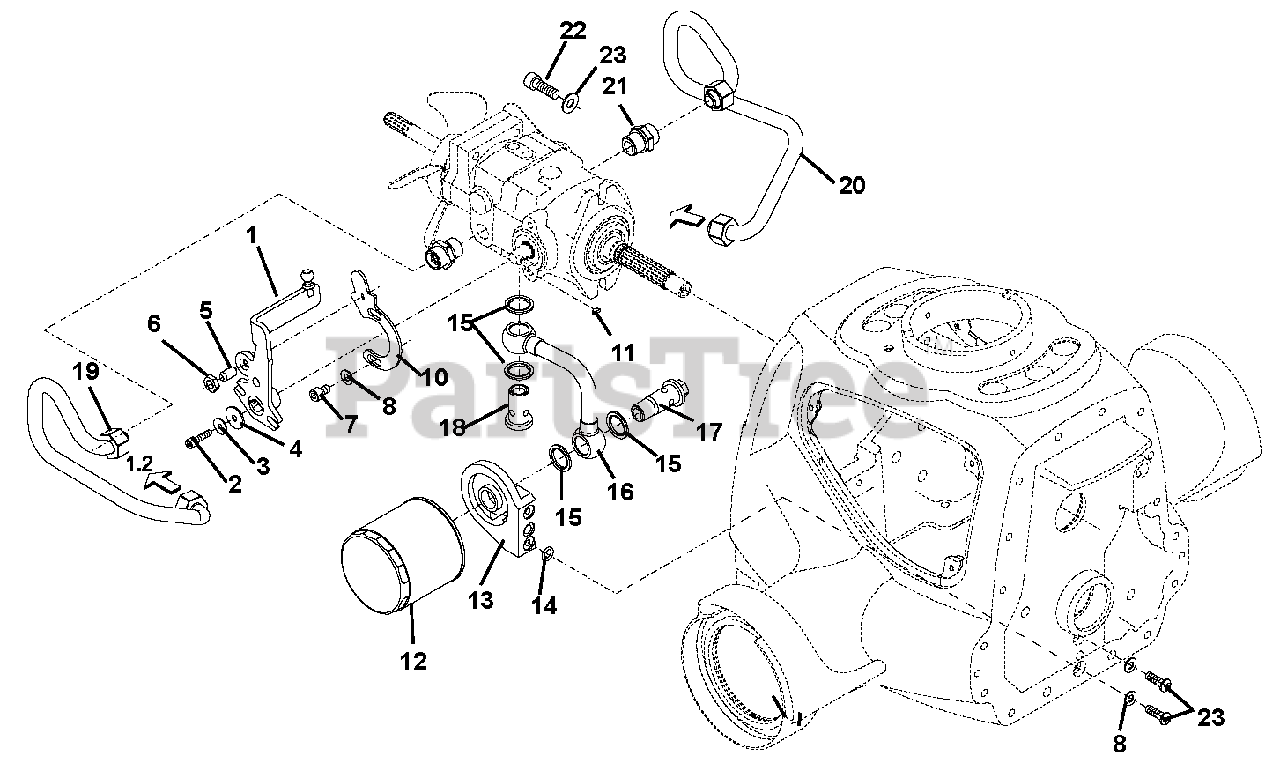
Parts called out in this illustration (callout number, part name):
1	Rod, Shift
2	Screw, M6 x 25
3	Washer, Form B 6.1/18.2 x 1.4
4	Washer, 7 x 25 x 1.8
5	Piece, Pressure with Ball M10 x 19
6	Nut, Hex M10
7	Screw, M8 x 12
8	Washer, Form S 8.2/16.2 x 1.4
9	Centralizing
11	Filter, Suction
13	O-Ring, 10.78 x 2.62
14	Seals, Bonded 20.7 x 30 x 2
15	Manifold, Inlet
18	Pipe, Hydraulic Left
19	Pipe, Hydraulic Right
21	Screw, M10 x 30
22	Washer, Form M 10.2/22.25 x 1.6
23	Screw, M8 x 25
